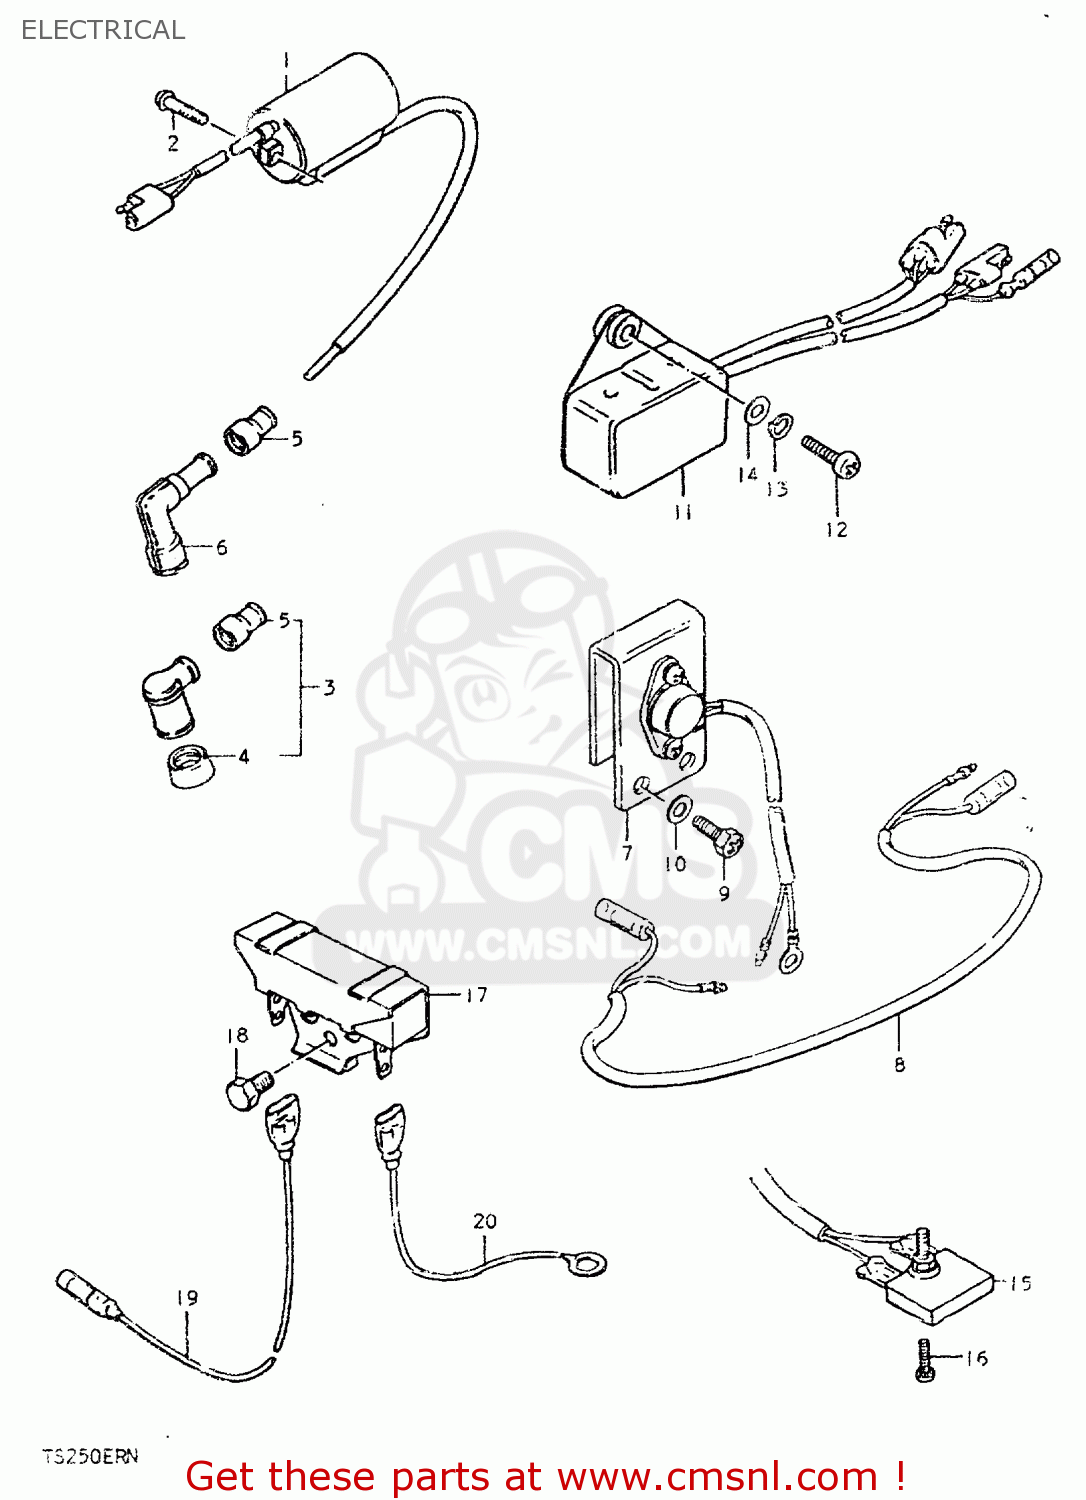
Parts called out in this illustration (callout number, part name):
1	COIL ASSY,IGNITION
2	SCREW 5X20
5	SEAL,SPARK PLU
6	CAP,SPARK PLUG
7	REGULATOR ASSEMBLY
9	SCREW(5X12)
10	WASHER
11	CDI UNIT
12	SCREW
13	LOCK WASHER
14	WASHER
15	RECTIFIER ASSEMBLY
16	SCREW
